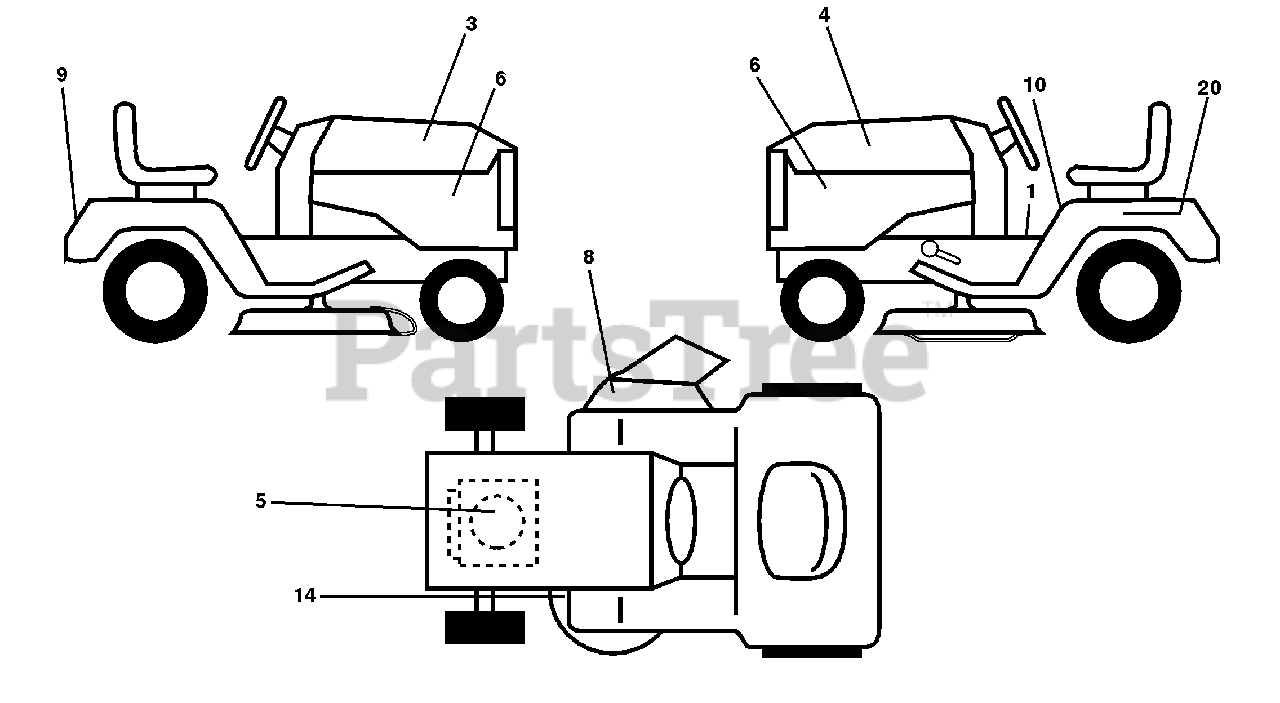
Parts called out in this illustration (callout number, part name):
1	Decal Oper. Step Thru Eng/Fr
3	Decal Hood RH
4	Decal Hood LH
5	Decal HP Engine
6	Decal Pnl Side
8	Decal Warning
9	Decal Fender Husq
10	Decal Fender Danger Eng/Fr
14	Decal V-Belt Schematic
20	Decal Bat Dan/Psn
MK380	Mulcher Kit with Blades
